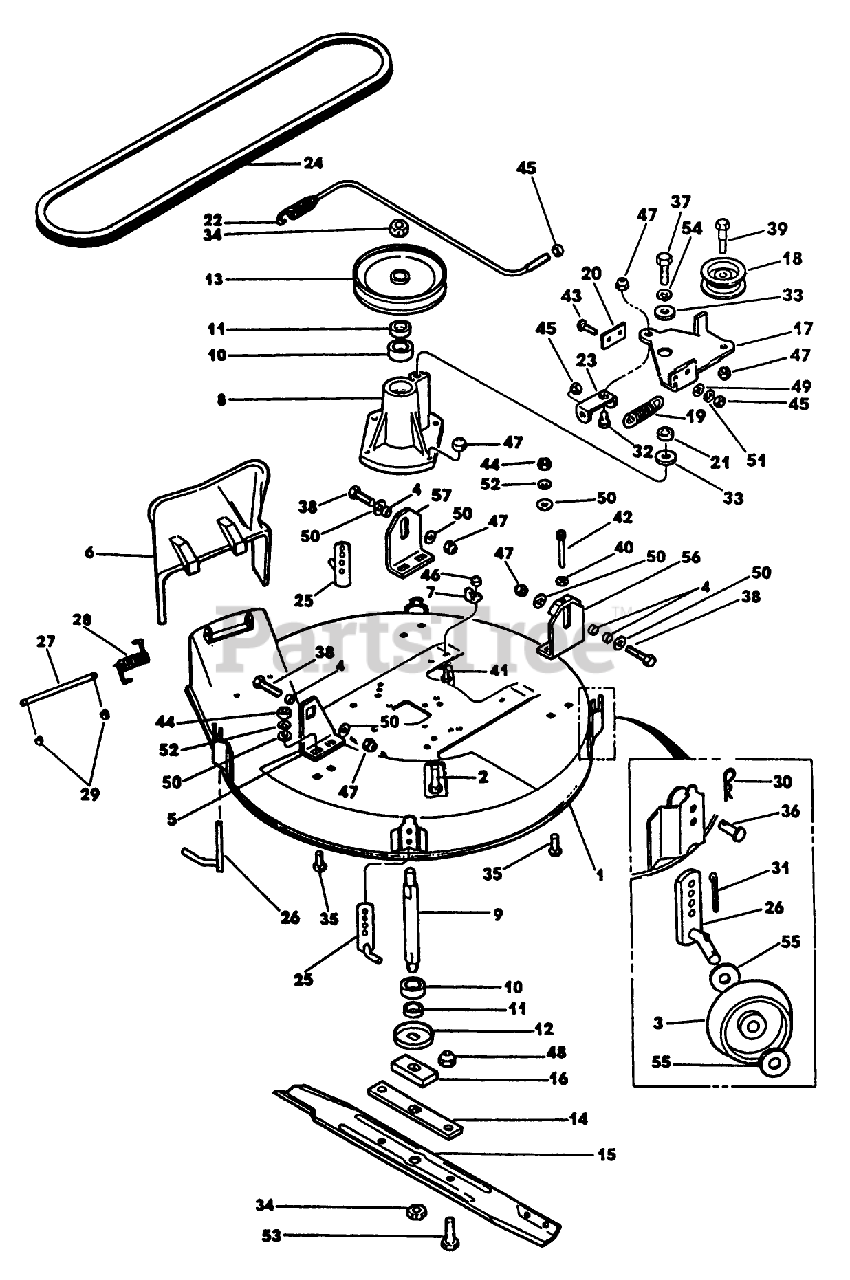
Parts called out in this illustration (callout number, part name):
3	WHEEL-GAGE
4	BUSHING
6	EXTENSION -CHUTE
7	BRKT-CLUTCH SPG *FORD BLUE
8	HOUSING,MOWER SPINDLE
9	SHAFT-SPINDLE
11	SPACER
19	SPRING
24	V-BELT
26	LH GAGE WHL WA*B
27	SHAFT - CHUTE
29	E-RING
30	PIN-HAIR
33	WASHER
34	LOCKNUT-SPECIAL
36	PIN - CLEVIS
41	SCREW-HH
44	NUT
45	NUT
46	NUT-LOCK, CONE
47	NUT-LOCKING
48	NUT-HEX CONE LOK
50	WASHER
52	WASHER
53	SCREW
57	BRKT REAR HNGE *F
